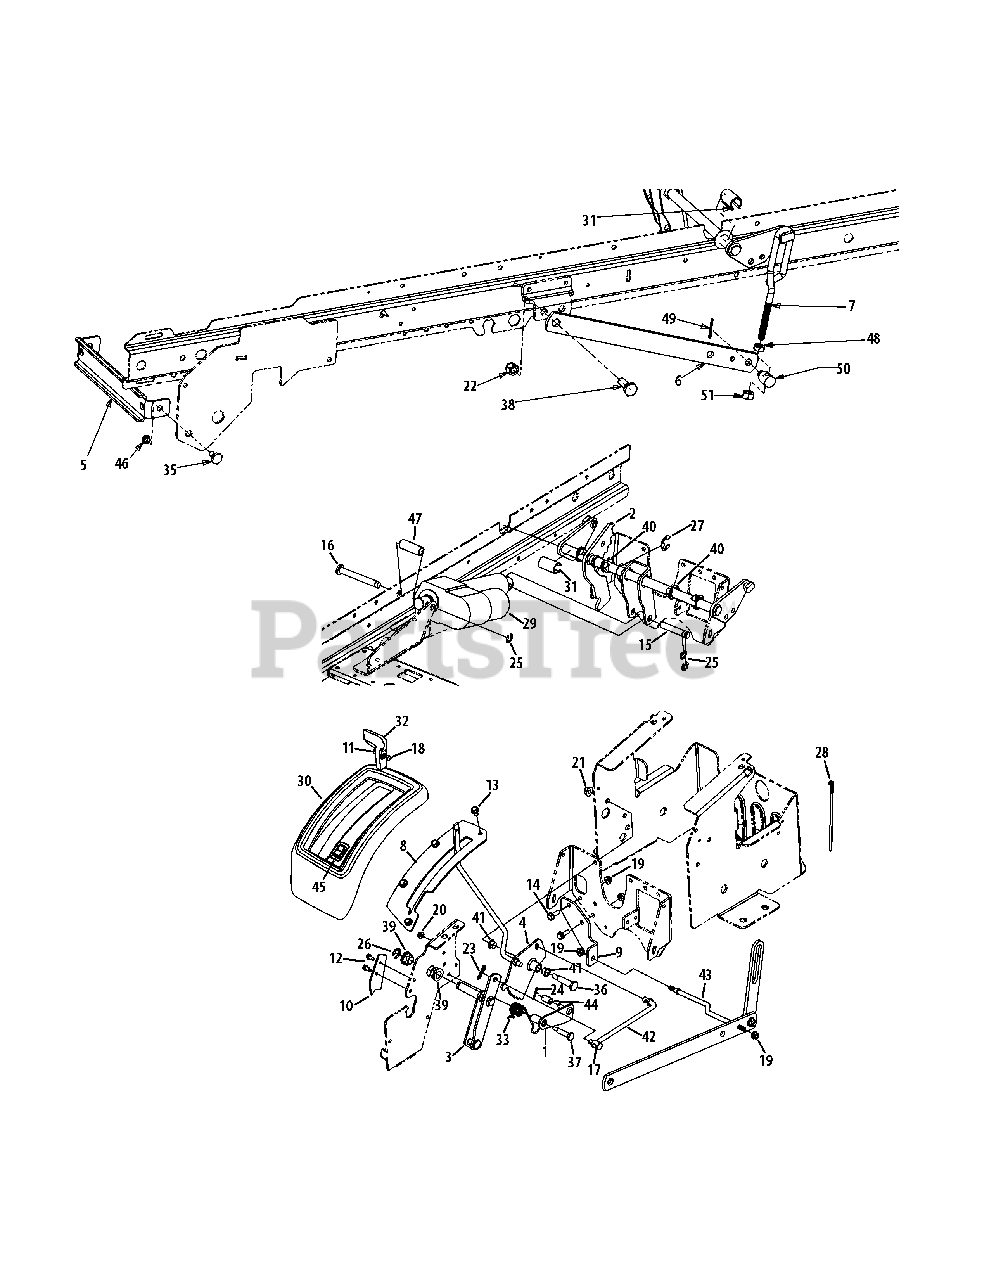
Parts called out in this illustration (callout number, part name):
1	Hub Lift Assembly
2	Shaft Assembly, Electric Lift
3	Deck Height Adjustment
4	Lift Lever Bracket Assembly
5	Front Hanger Bracket
7	Link, Adjustment Lift
9	Sway Bar Mount Bracket
10	Bearing Stop Plate
11	Machine Screw, #10-24 x .625
12	Hex Washer Screw, 1/4-20 x .500
13	Hex Washer Screw, 5/16-18 x .625
14	Hex Washer Screw, 5/16-18 x .875
15	PIN, .50 x 3.5
16	Clevis Pin, .50 x 4.0
17	Ferrule, 3/8-24 x .375
18	Hex Lock Nut, #10-24
19	Flange Lock Nut, 5/16-18
20	Flange Lock Nut, 1/4-20
21	Flange Lock Nut, 3/8-16
22	Hex Lock Nut, 1/2-13
23	Bow-Tie Cotter Pin, 72
24	Cotter Pin, .125 x .75
25	E-Ring, .500
26	E-Ring, .625
27	E-Ring, .875
28	Cable Tie, 3/16 x .05 x 7.4
29	Plow Lift Actuator
30	Lift Cover
32	Electric Lift Knob
33	Torsion Spring
34	Shoulder Screw, 1/2 x .29
35	Shoulder Screw, .500 x .295
36	Shoulder Screw, .498 x 1.635
37	Shoulder Screw, .374 x 1.375
38	Shoulder Screw, 1/2-13 x .625 x .36
39	Hex Flange Bearing
40	Hex Flange Bearing, .78
41	Flange Bearing, .500 x .34
42	Electric Lift Rod Adjuster
43	Anti-Sway Deck Rod
44	Spacer, .35 x .5 x .851
45	Plow Lift Switch
46	Jam Lock Nut, 3/8-16
47	Spacer, .55 ID x .75 OD x 2.06
48	Nut, Hex Jam 1/2-13
49	Pin, Cotter 1/8 x 1.25
50	Ferruel. Lift Link
51	Nut, Hex Nylok 1/2-13
